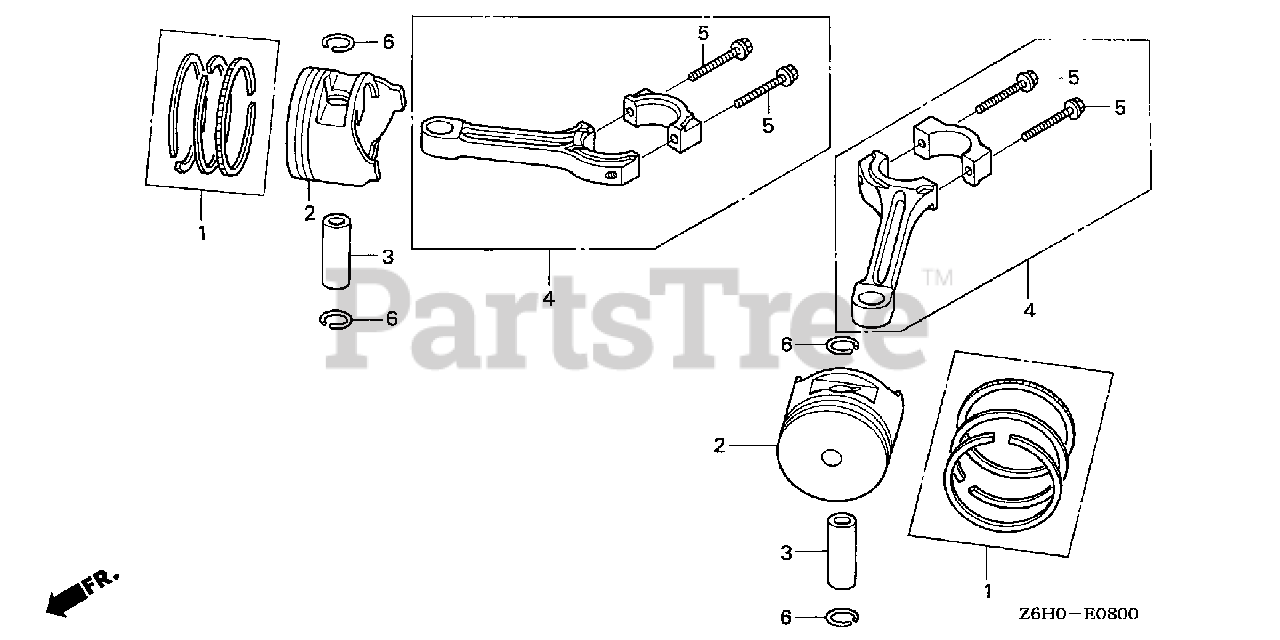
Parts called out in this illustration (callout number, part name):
1	RING SET, PISTON (STD.) (TEIKOKU)
1	RING SET, PISTON (0.25) (TEIKOKU)
1	RING SET, PISTON (0.50) (TEIKOKU)
1	RING SET, PISTON (0.75) (TEIKOKU)
2	PISTON (STD)
2	PISTON (0.25)
2	PISTON (0.50)
2	PISTON (0.75)
3	PIN, PISTON
4	ROD ASSY., CONNECTING
5	BOLT, CONNECTING ROD (6X37)
6	CLIP, PISTON PIN (18MM)
